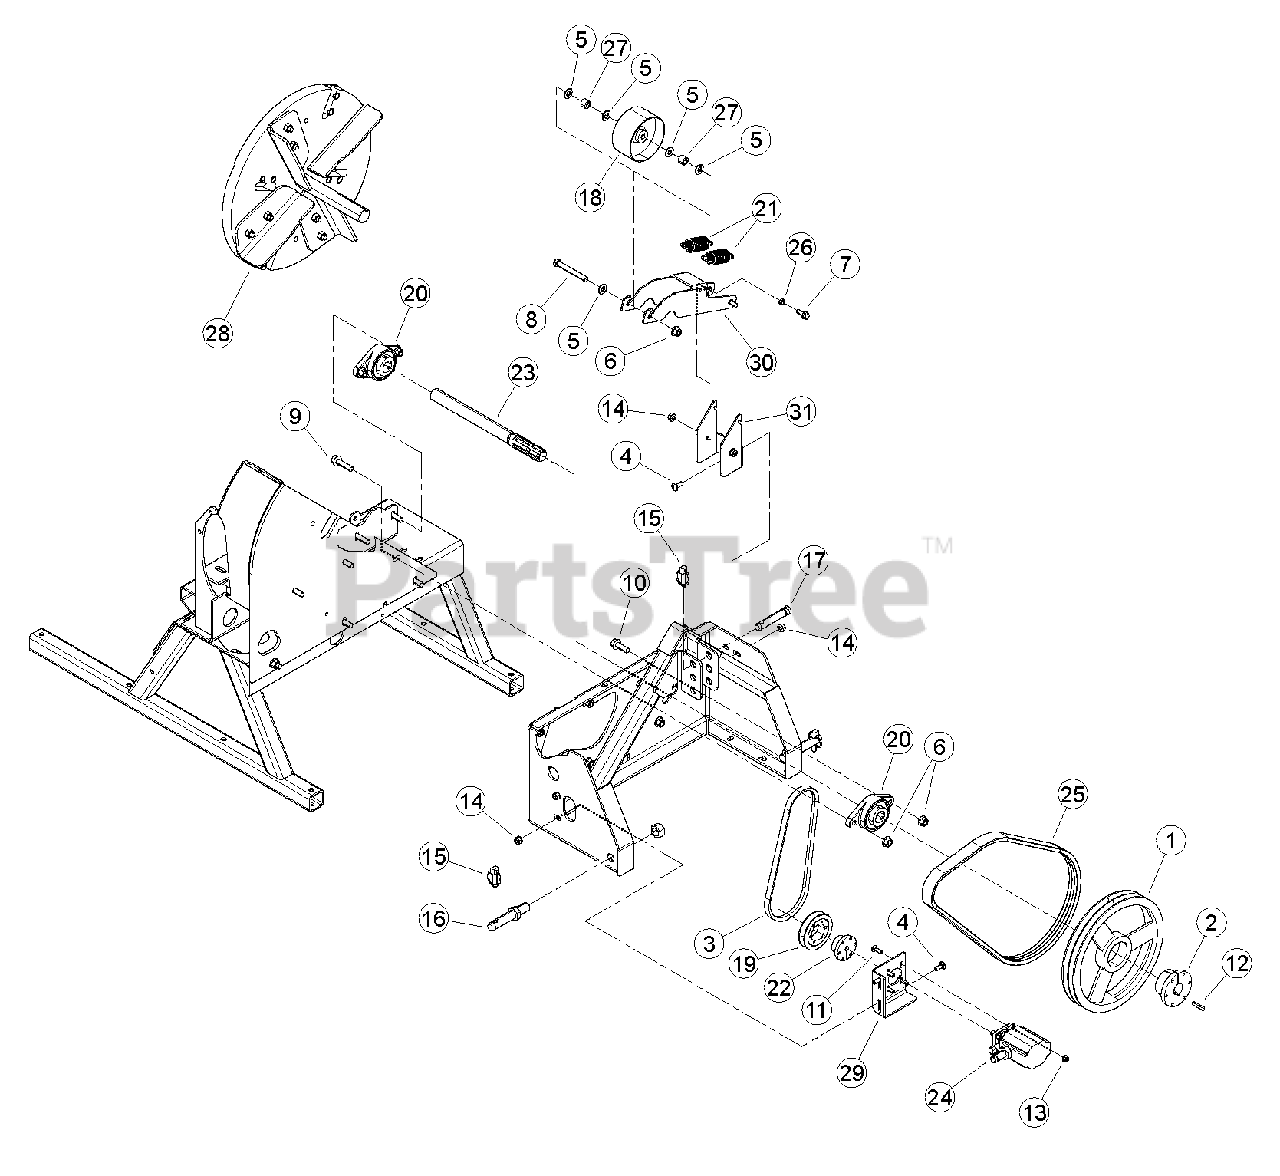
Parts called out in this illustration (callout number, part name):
1	SHEAVE, 2B12.4 SK
2	BUSHING, SK 1-1/4"
3	BELT, 4L350
4	BOLT, 3/8-16 X 1 GR5 CRG
5	WASHER, 1/2 SAE FLAT
6	NUT, 1/2-13 NYLOCK FLANGE
7	BOLT, 3/8 X 1 FLANGE NC
8	BOLT 1/2 X 4 HEX CPS G5 ZP
9	BOLT, 1/2-13 X 2 FLANGE GR5 CZP
10	BOLT, 1/2-13 X 1-1/2 GR5 FLANGE NC
11	BOLT, 5/16-18 X 1 GR5 CRG
12	KEY, 1/4 SQ X 1-1/2 LG PLAIN
13	NUT, 5/16-18 NYLOCK FLANGE
14	NUT, 3/8-16 NYLOCK FLANGE
15	PIN, 7/16 X 1-1/4 LYNCH
16	PIN, LIFT ARM 7/8 X 5" LG
17	PIN, TOP LINK 3/4 X 4-1/2" LG
18	PULLEY, IDLER 5" X 2.50"
19	SHEAVE, 1B3.6 SH
20	BEARING, 1-1/4" DIA 2 BOLT FLANGE
21	SPRING, 1.25 OD X 3.50 LG X .148 WD
22	BUSHING, SH 1/2"
23	SHAFT, 6 SPLINE 5" CHIPPER
24	PUMP, 2 STAGE CW HI/LO 0.605 DISP.
25	BELT, 2RBX56
26	SPACER, IDLER PIVOT
27	SPACER, .81 X .620
28	ASSEMBLY, 5" ROTOR
29	WELDMENT, PUMP MOUNT
30	ARM, INSIDE IDLER
31	BRACKET, INSIDE IDLER ARM MOUNTING
